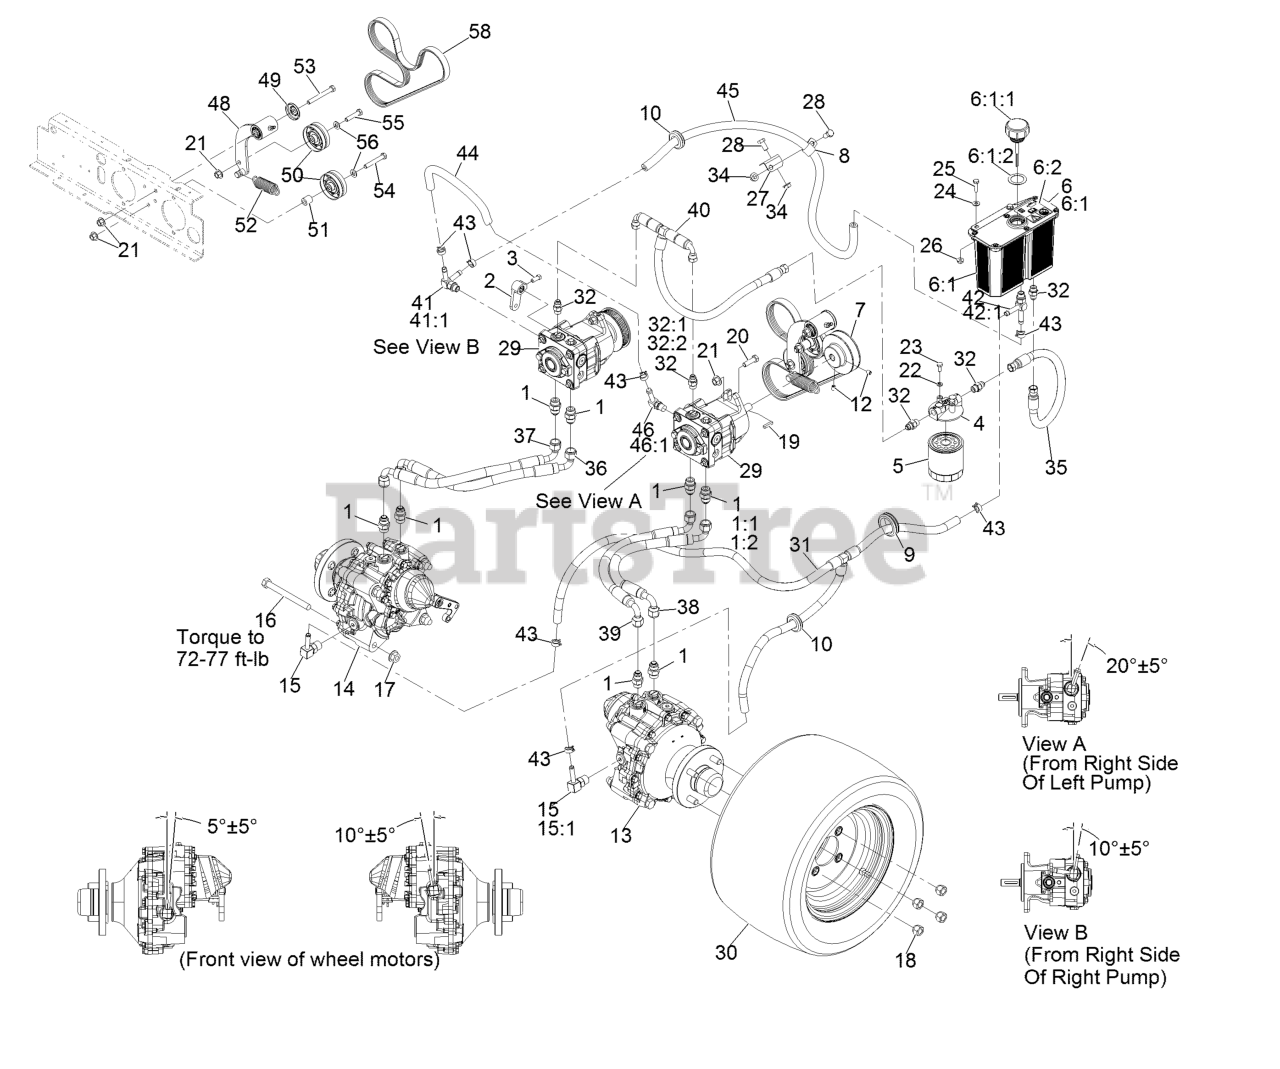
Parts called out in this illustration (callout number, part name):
1	Adapter-Straight
1:1	O-Ring-SAE #8
1:2	O-Ring-37 Flare #8
2	Arm-Control, Pump
3	Screw-Set, SQH 5/16-18 X 3/4
4	Filter-Head
5	Element, Oil Filter
6	Reservoir ASM
6:1	Reservoir-HYD
6:1:1	Reservoir Cap ASM
6:1:2	Gasket-Cap
6:2	Decal-Warning
8	Clip-Loom 5/8
9	Grommet
10	Grommet
12	Setscrew-5/16-18 X 3/8
13	Motor-HYD, LH
14	Motor-HYD, RH
15	Fitting-HYD, 90 DEG
15:1	O-Ring
16	Screw-HH 1/2-13 X 5
17	Nut-Whizlock 1/2-13
18	Nut-Lug 1/2-20
19	Key-5Mm X 5Mm X 25Mm
20	Screw-HH 3/8-16 X 1 1/4
21	Nut-Whizlock 3/8-16
22	Washer-Lock 1/4 Heavy
23	Screw-HH 1/4-20 X 5/8
24	Washer-1/4 SAE
25	Screw-HH 1/4-20 X 1
26	Nut-Whizlock 1/4-20
27	Bracket-Clamp
28	Screw-HH 3/8-16 X 3/4
29	12Cc Hydro Pump ASM
30	Tire And Wheel ASM
31	Hydraulic Hose ASM
32	Adapter-Straight
32:1	O-Ring-SAE #6
32:2	O-Ring-37 Flare #6
34	Nut-Whizlock 3/8-16
35	Hydraulic Hose ASM
36	Hydraulic Hose ASM
37	Hydraulic Hose ASM
38	Hydraulic Hose ASM
39	Hydraulic Hose ASM
40	Hydraulic Hose ASM
41	Adapter-Tee Special
41:1	O-Ring
42	Adapter-Running Tee
42:1	O-Ring
43	Clamp-Hose 11/16
44	Hose-HYD
45	Hose-HYD
46	Fitting-Elbow, 90
46:1	O-Ring
48	Short Idler ASM
49	Guard-Top
51	Spacer-Mounting, Steering
53	Screw-HH 3/8-16 X 3-1/4
54	Screw-HH 3/8-16 X 2 1/2
55	Screw-HH 3/8-16 X 1 3/4
56	Washer-3/8 SAE
58	Belt
